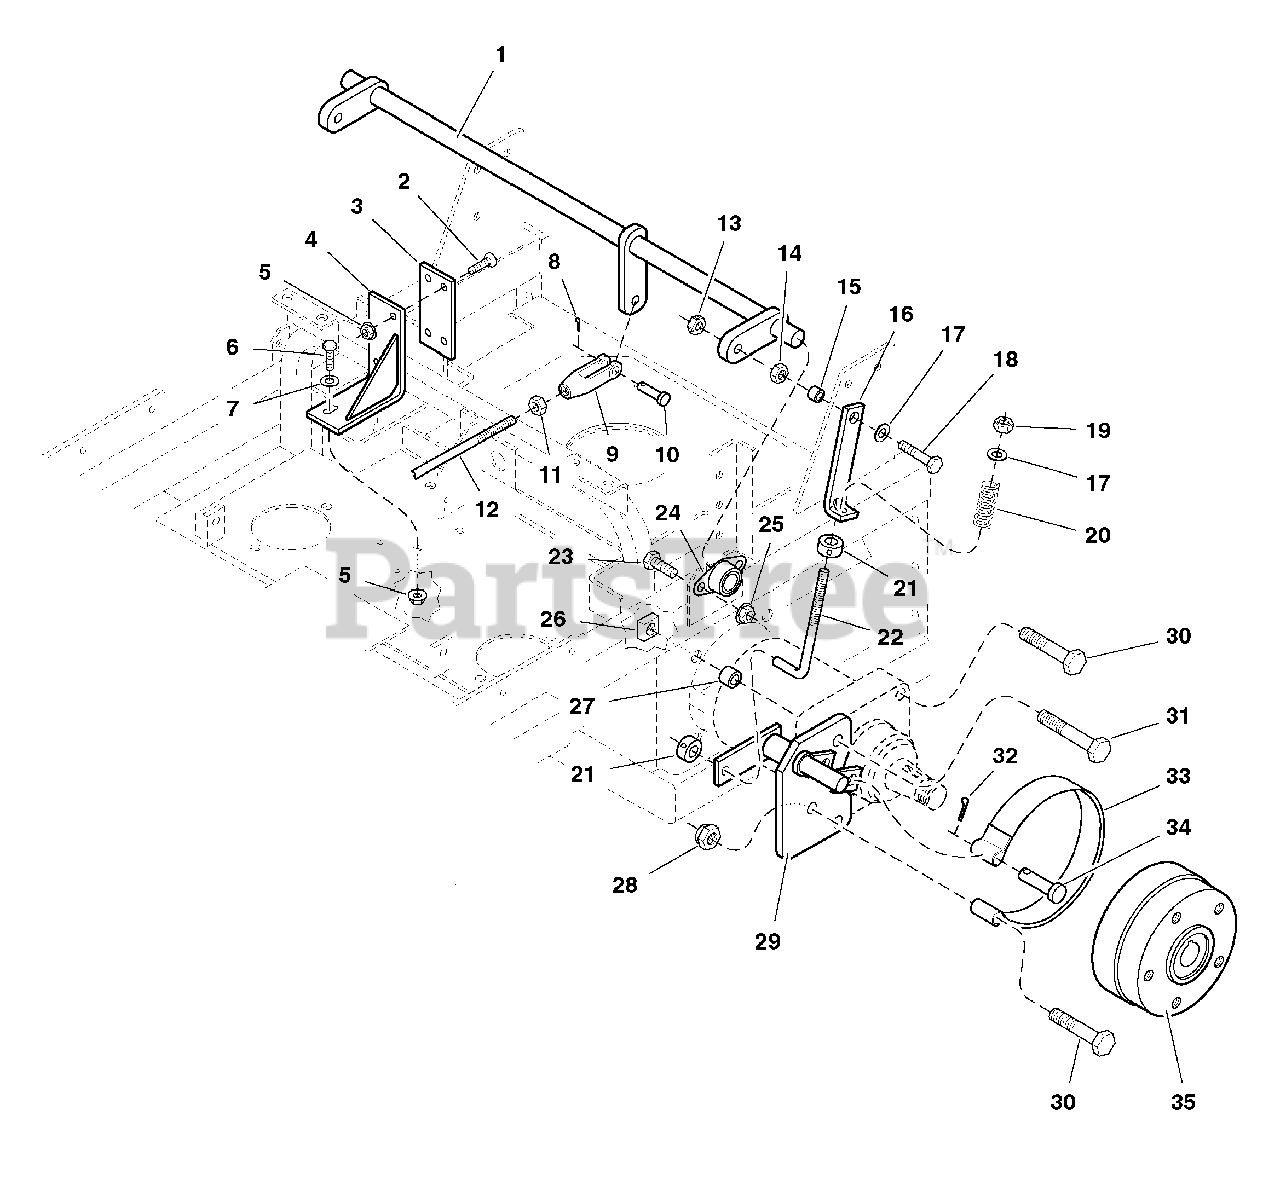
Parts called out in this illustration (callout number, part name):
1	BRAKE CROSS SHAFT
2	SCREW, 5/16-18 X 1, PHILLIPS HD, BZ
3	FRICTION PLATE
4	SUPPORT, Brake Shaft
5	NUT, Hex, Serrated Flange, 5/16-18
6	CAPSCREW, Hex Hd, 5/16-18 x 1
7	WASHER, 5/16
8	COTTER PIN
9	CLEVIS, 3/8-24
10	PIN, Clevis, 3/8 x 1
11	NUT, Hex, 3/8-24
12	BRAKE CONNECTING ROD
13	NUT, Hex, Side Lock, 3/8-16
14	NUT, Hex, 3/8-16
15	PIVOT SLEEVE
16	LINK, BRAKE LOCK - BLK
17	WASHER, 3/8
18	CAPSCREW, Hex Hd, 3/8-16 x 1-1/2
19	NUT, Hex, Top Lock, 3/8-16
20	BRAKE SPRING
21	COLLAR, Set, 3/8
22	ROD, Brake Adjustment
23	CAPSCREW, Hex Hd, 3/8-16 x 3/4
24	BEARING, Flange
25	NUT, Hex, Serrated Flange, 3/8-16
26	NUT, Square, 1/2-13
27	SPACER, Wheel Motor
28	NUT, Hex, Nylon Lock, 1/2-13
29	BRAKE BAND SHAFT-LH
30	CAPSCREW, Hex Hd, 1/2-13 x 3
31	CAPSCREW, Hex Hd, 1/2-13 x 3-1/2
34	PIN, Clevis, 1/2 x 2
